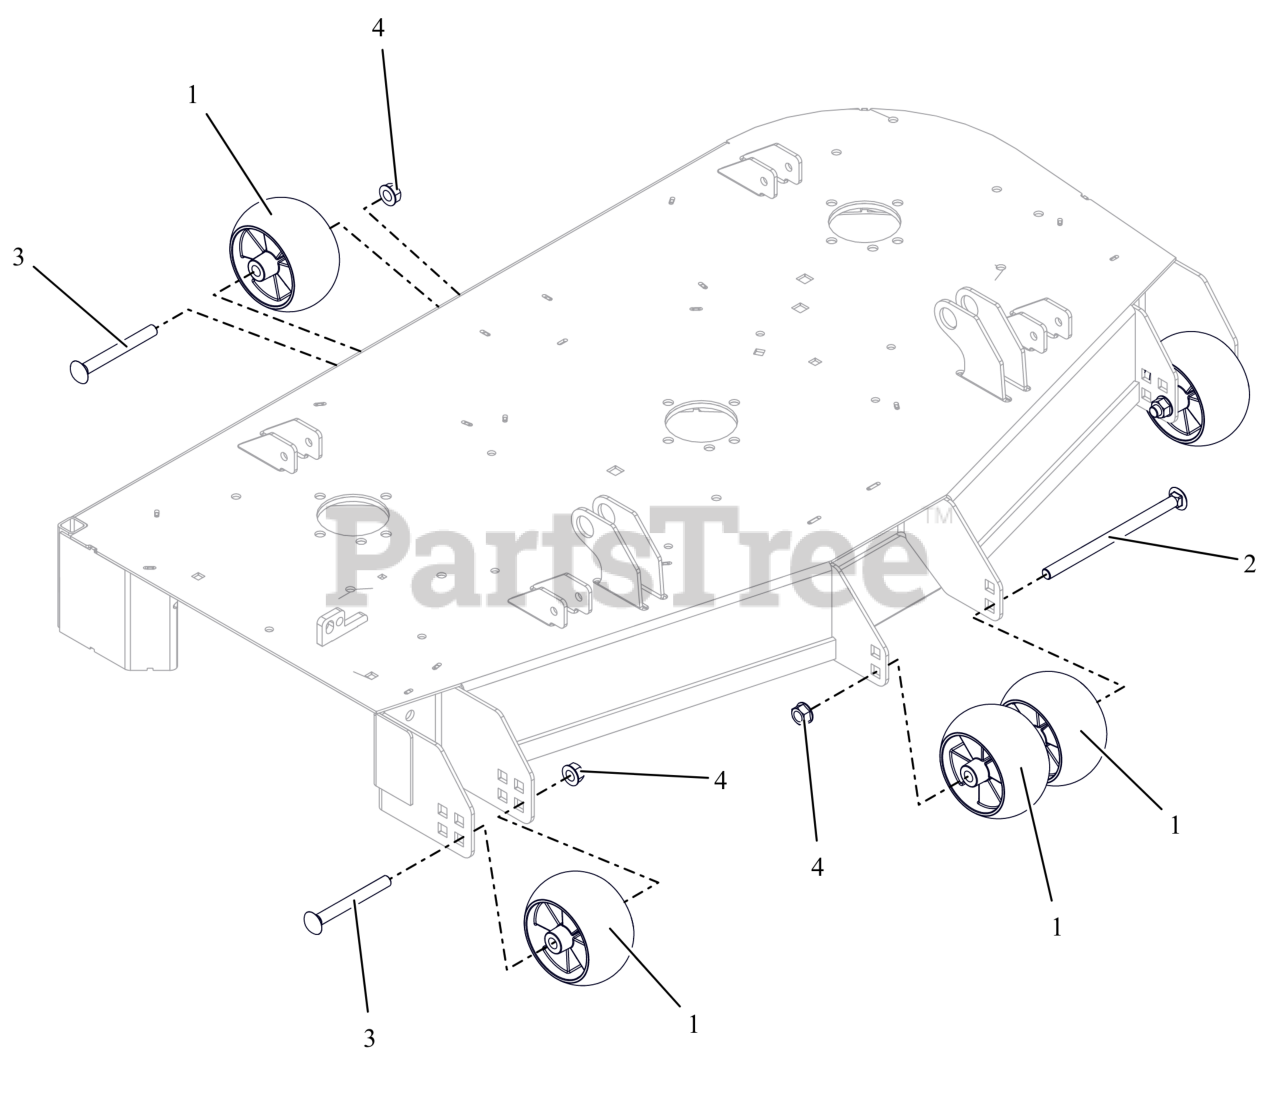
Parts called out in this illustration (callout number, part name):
1	WHEEL, ANTI SCALP - 5X3 CTR W/RIBS
2	BLT-RHSN .50-13X8.00 G5 ZCC NS
3	BLT-RHNS .50-13X4.50 G5 ZCC NS
4	NUT-LK-CTR-FLG .500-13 GG ZCC
